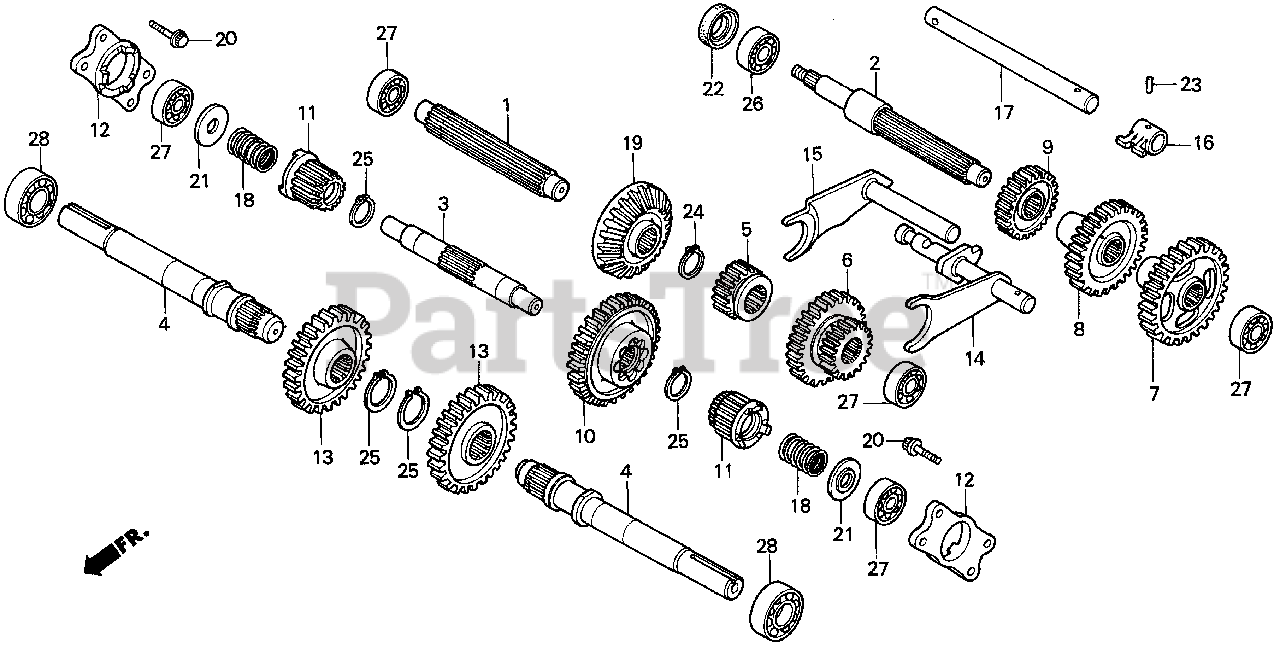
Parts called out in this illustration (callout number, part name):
1	SHAFT, INPUT
2	COUNTERSHAFT
3	SHAFT, SIDE CLUTCH
4	SHAFT, WHEEL
5	GEAR, INPUT SHAFT CHANGE (19T)
6	GEAR, CHANGE (22T-31T)
7	GEAR, FIRST IDLE (39T)
8	GEAR, SECOND IDLE (23T)
9	GEAR, COUNTERSHAFT (36T)
10	GEAR, SIDE CLUTCH DRIVING (49T)
11	GEAR, SIDE CLUTCH (16T)
12	CASE, SIDE CLUTCH BEARING
13	GEAR, FINAL (35T)
14	FORK, INPUT SHAFT SHIFT
15	SWINGARM, SHIFT
16	ARM, FORK SELECTING
17	SHAFT, SHIFTING
18	SPRING, SIDE CLUTCH
19	GEAR, DRIVEN BEVEL
20	BOLT, SPECIAL (8MM)
21	WASHER, CLUTCH SPRING
22	OIL SEAL (20X31X7)
23	PIN, SPRING (5X22)
24	CIRCLIP (OUTER) (22MM)
25	CIRCLIP (OUTER) (25MM)
26	BEARING, RADIAL BALL (6004)
27	BEARING, RADIAL BALL (6203)
28	BEARING, RADIAL BALL (6205)
